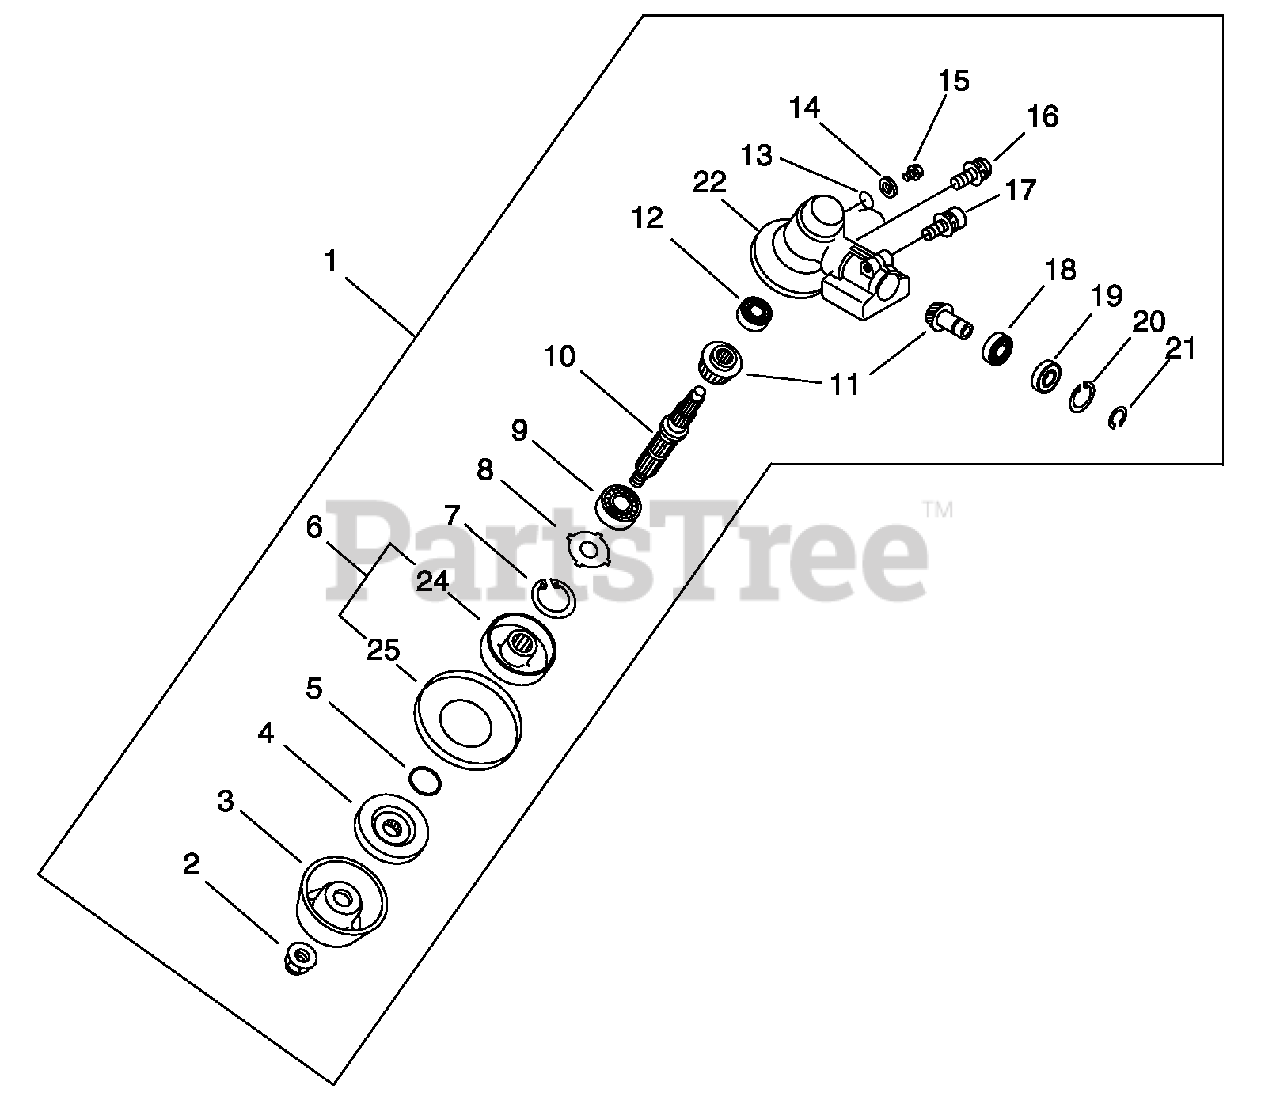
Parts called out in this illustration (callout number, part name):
1	GEAR CASE ASSY
2	NUT - 10
4	ADAPTOR, BLADE - LOWER
5	O-RING - 12
6	BLADE ADAPTER KIT
7	RING, RETAINING - 32
9	BEARING, BALL - 6201
10	GEAR - SHAFT
11	GEAR SET
12	BEARING, BALL - 626
14	WASHER - 8
15	BOLT - 8X8
16	SCREW - 5X10
17	SCREW - 6X25
18	BEARING, BALL - 6900
19	BEARING, BALL - 6900Z
20	RING, RETAINING - 22
21	RING, RETAINING - 10
22	CASE, GEAR
24	ADAPTOR, BLADE - UPPER
25	RETAINER, BLADE
